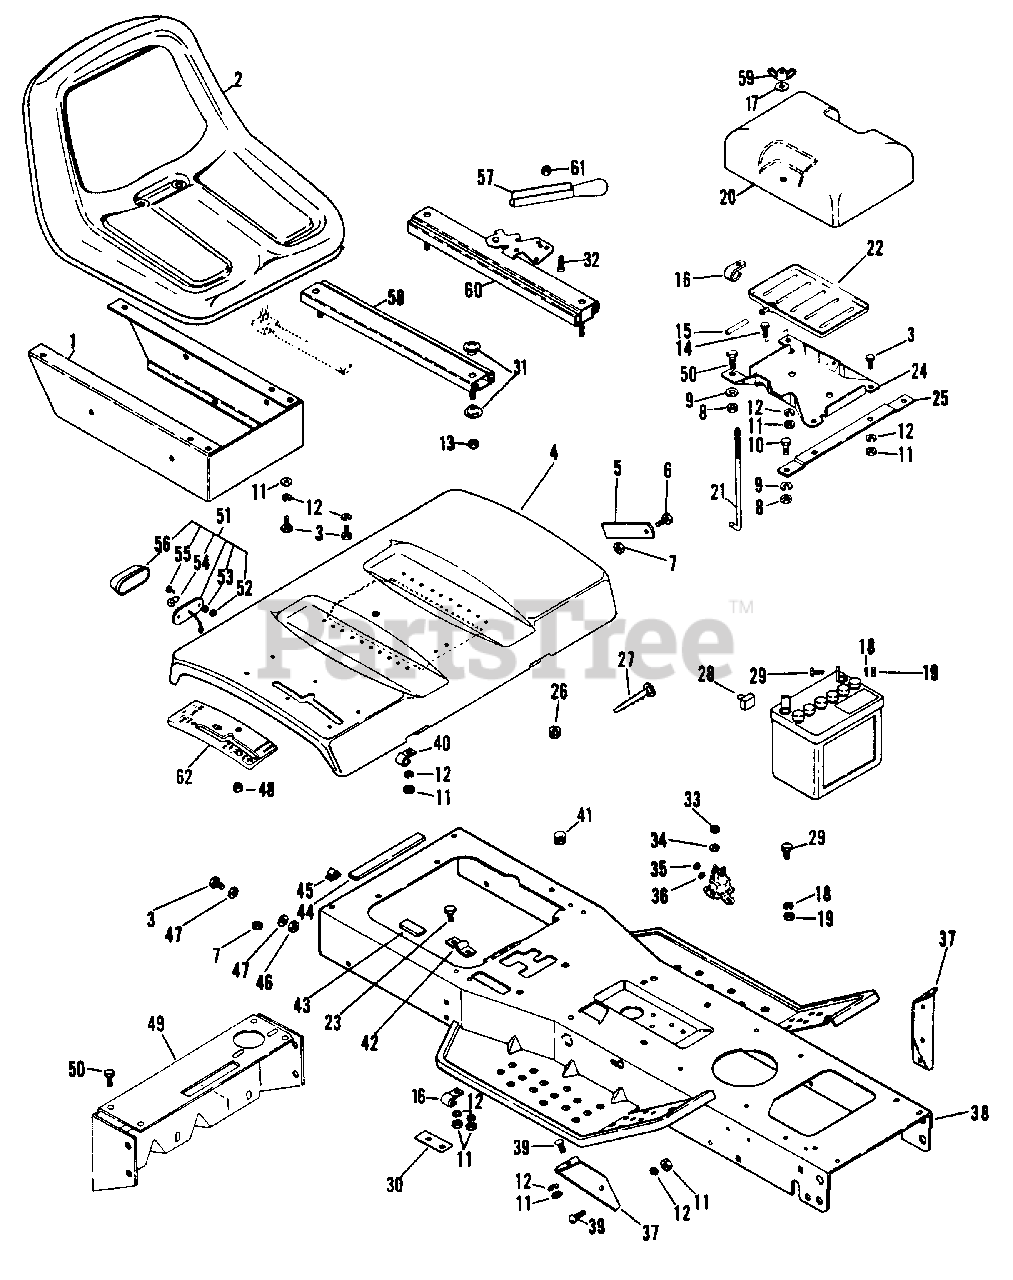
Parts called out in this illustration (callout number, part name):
1	FRAME, SEAT
2	SEAT, HIGH BACK
3	BOLT, HEX 5/16-18X.75
4	DECK, REAR
5	CATCH, DECK
6	BOLT, HEX 3/8-16X.625
7	NUT, LOCK 3/8-16
8	NUT, HEX 3/8-16
9	WASHER, LOCK 3/8 REG.
10	BOLT, HEX 3/8-16X.75
11	NUT, HEX 5/16-18
12	WASHER, LOCK 5/16 SP
13	NUT, LOCK 5/16-18
14	BOLT, HEX 5/16-18X1.00
15	HOSE, DRAIN
16	J-CLAMP
17	WASHER, FLAT .281X.625X.065
18	WASHER, LOCK 1/4 REG.
19	NUT, HEX 1/4-20
20	COVER, BATTERY
21	BOLT, HOLD DOWN
22	TRAY, PLASTIC BATTERY
23	BOLT, HEX 5/16-18X.50
24	TRAY, BATTERY
25	STRAP
26	GROMMET
27	TIE DOWN
28	INSULATOR
29	BOLT, HEX 1/4-20X.875
30	STRAP
31	SPACER
32	SCREW, MACHINE 10-24 X.625 P/HD
33	NUT, JAM 5/16
34	WASHER, LOCK 5/16 INT. TOOTH
35	NUT, HEX 10-32
36	WASHER, LOCK #10 EXT.
37	STRUT, L.H. FOOTBOARD
37	STRUT, R.H. FOOTBOARD
38	FRAME, MAIN
39	BOLT, CARRIAGE 5/16-18X.75
40	CLIP
41	PLUG, HOLE
42	BRACE
43	TAPE, FOAM
44	TAPE, FOAM
45	BUMPER
46	NUT, LOCK 5/16-18
47	WASHER, FLAT .406X.812X.065
48	NUT, SELF-THREADING
49	DRAWBAR
50	BOLT, HEX 3/8-16X1.25
51	ASSEMBLY, TAILLIGHT
52	NUT, 10-24 HEX
53	WASHER, LOCK NO. 10 SP
55	SCREW, MACHINE 10-24X.50 PHD
56	LENS
57	HANDLE, SEAT ADJUSTER
58	ADJUSTER, SEAT
59	NUT, WING 1/4-20
60	ADJUSTER, SEAT W/LATCH
61	NUT, LOCK 10-24
62	INSERT, SHIFT
NS	DECAL, AMERICA
NS	DECAL, GRAVELY LOGO
NS	DECAL, BRAKE LOCK
NS	DECAL, FAN
NS	DECAL, TRANSMISSION DISCONNECT
